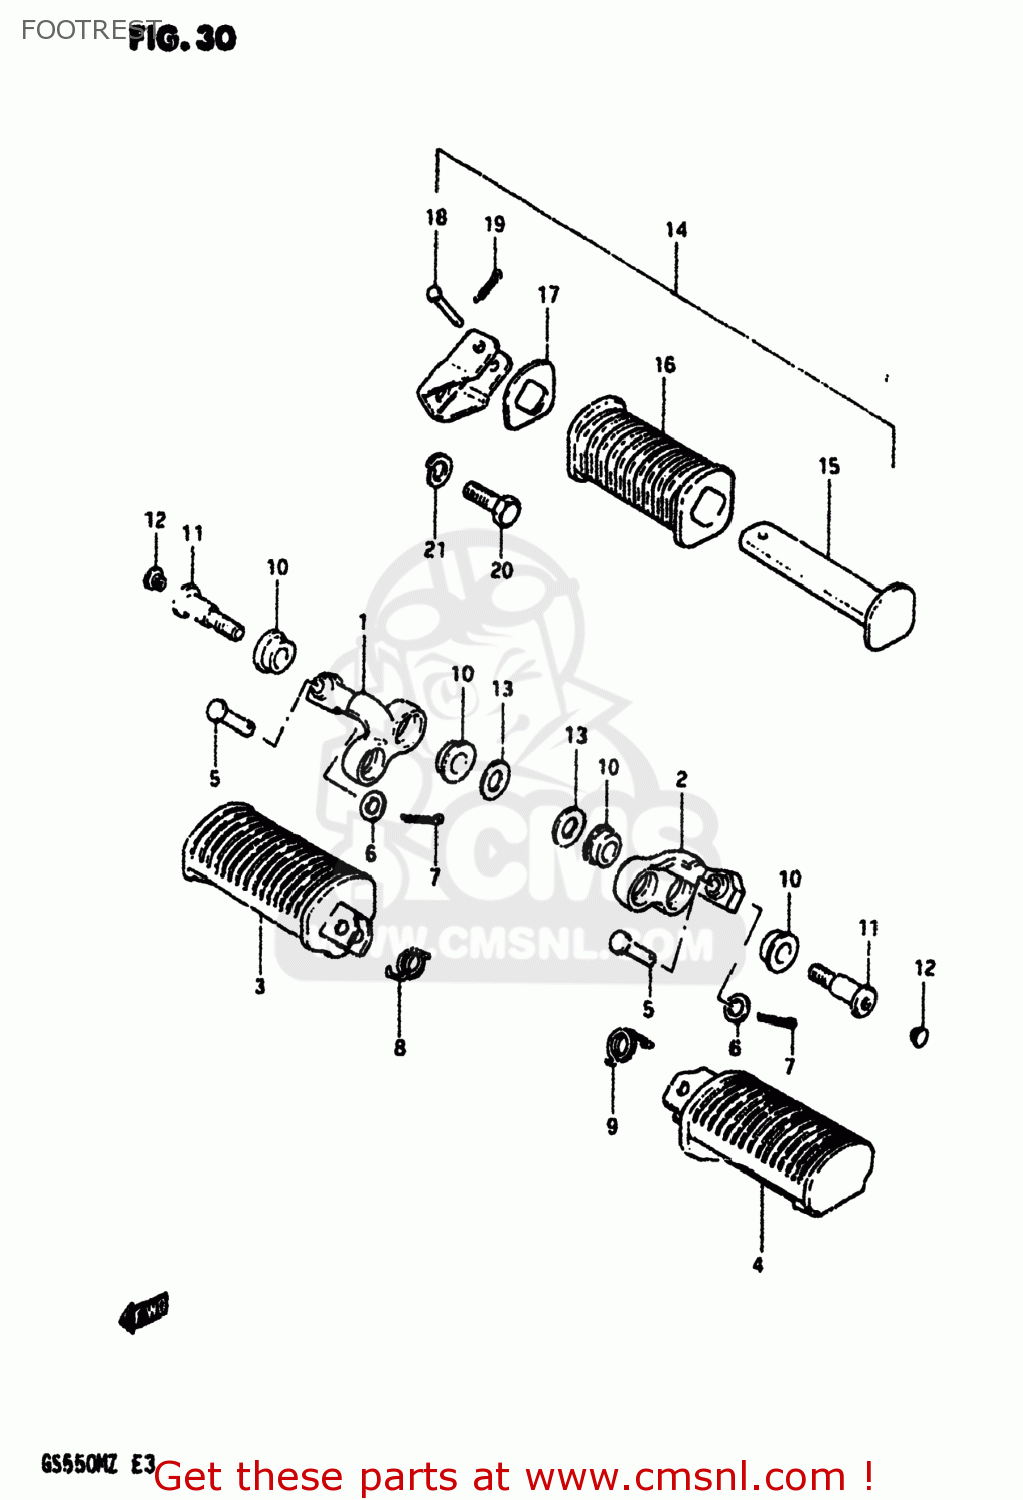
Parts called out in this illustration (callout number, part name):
1	BAR,FRONT FOOTREST,RIGHT
2	BAR,FRONT FOOTREST,LEFT
3	RUBBER,FOOTREST
4	FOOTREST
5	PIN
6	WASHER
7	PIN 20X20
8	SPRING
9	SPRING
10	BUSH
11	BOLT
12	CAP
13	WASHER(10.2X28X2.3)
14	FOOTREST ASSEMBLY,REAR,LEFT
15	BAR,REAR FOOTREST,LEFT
16	RUBBER,PILLION FOOTREST
17	WASHER,PILLION FOOTREST RUBBER
18	PIN
19	PIN 20X20
20	BOLT 10X20
21	LOCK WASHER
